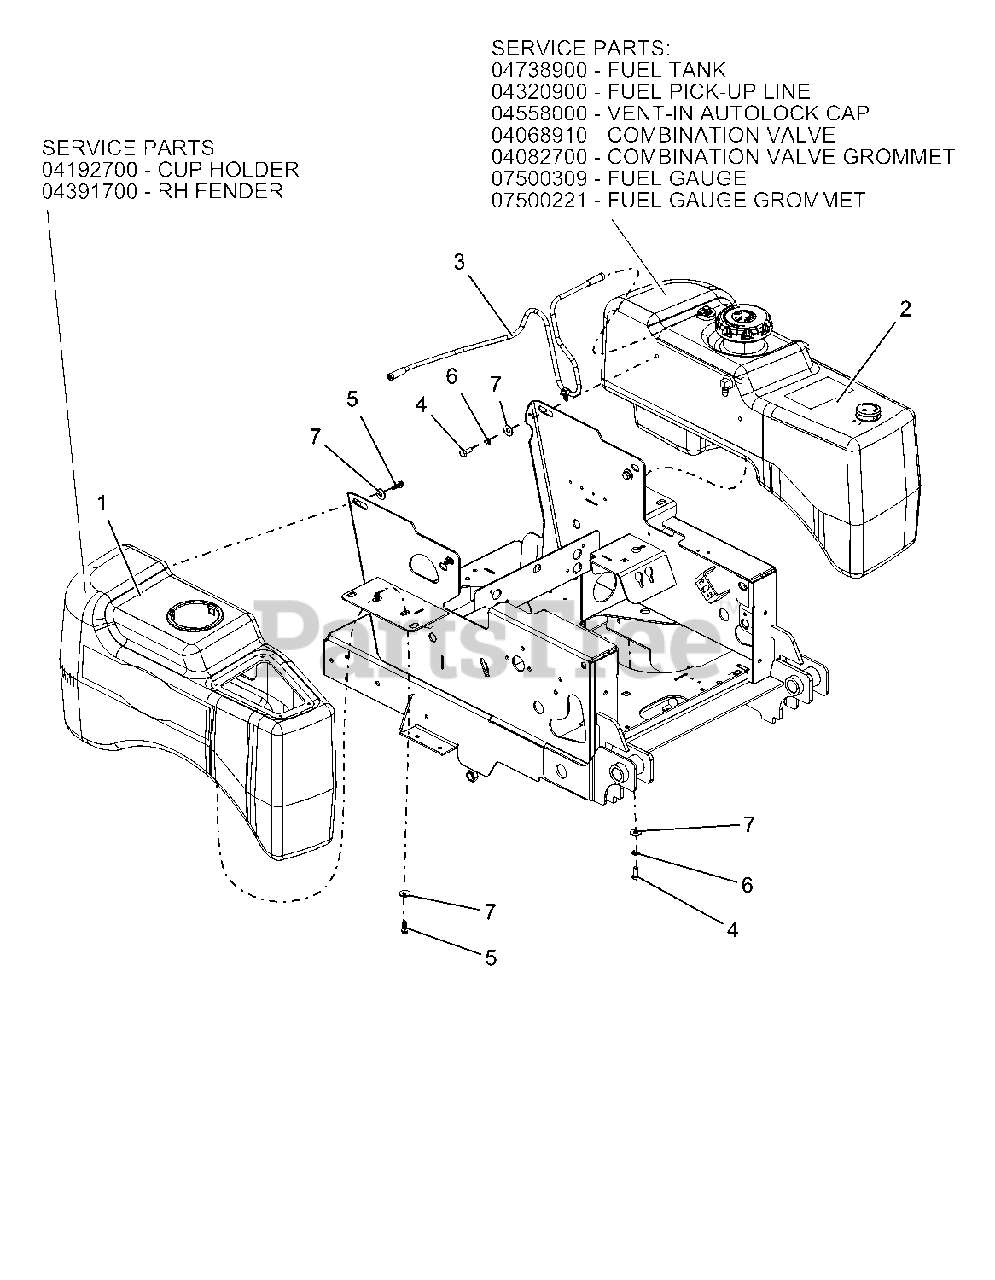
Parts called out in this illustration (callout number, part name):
1	ASM, FENDER W/CUPHOLDER
1	CUP HOLDER
1	RH FENDER
2	HD, FUEL TANK ASSEMBLY
2	FUEL TANK
2	FUEL PICK-UP LINE
2	VENT-IN AUTOLOCK CAP
2	COMBINATION VALVE
2	COMBINATION VALVE GROMMET
2	FUEL GAUGE
2	FUEL GAUGE GROMMET
3	KAWASAKI, VENT LINE HD/PRO-TURN
4	BLT-HEX .31-18X.75 GR5 YWZC
5	SCR-PLASTITE .25-10X.75 YWZC
6	WSHR-LK .31X.078 REG YWZC
7	WSHR-FL-STL.38X.875X.083 YWZC
